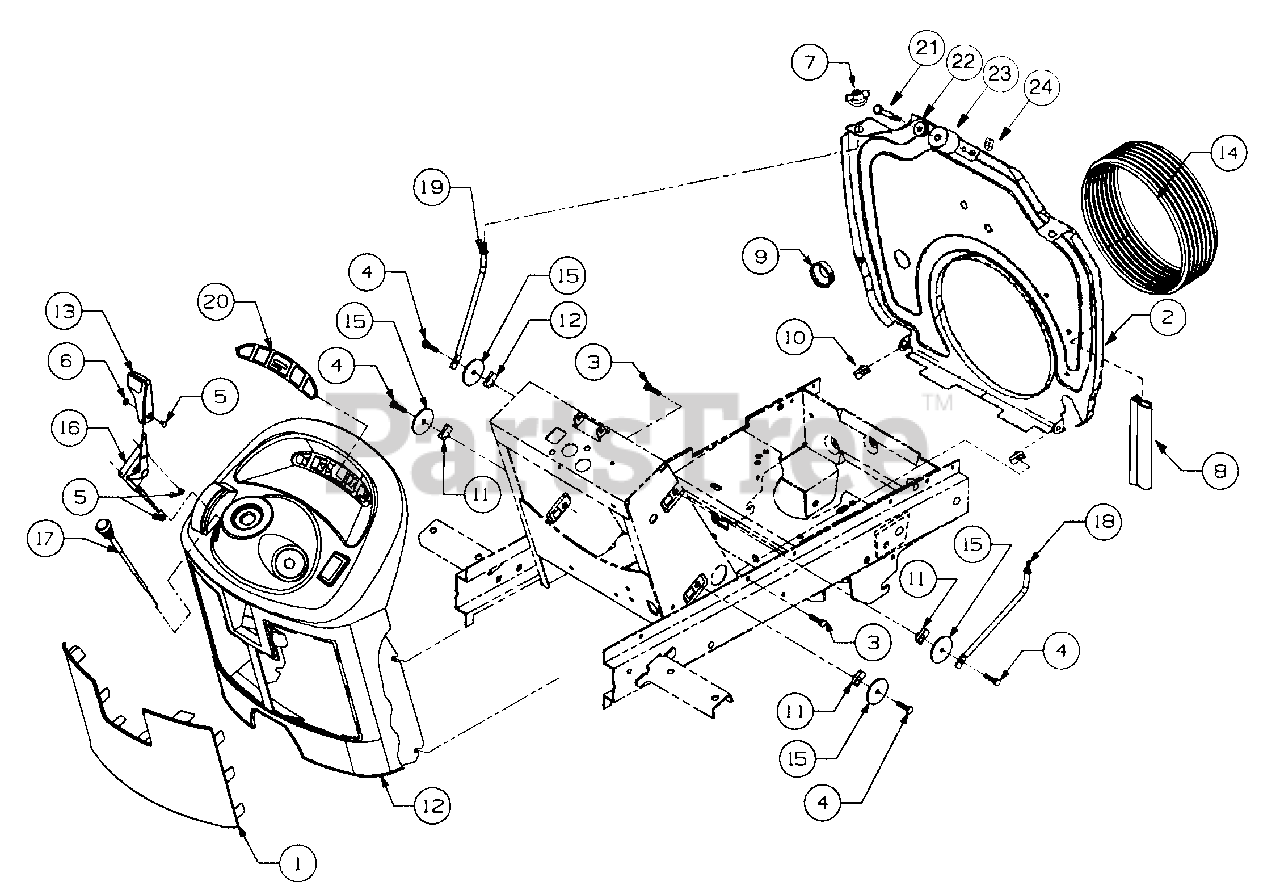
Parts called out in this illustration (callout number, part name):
2	Bulkhead, Lower
4	Screw, Hex Cap, 1/4-20 x 1.0
5	Screw, Cross Rec Truss Hd, #8-32 x.38
6	Nut, #8-32
7	Nut, Wing w/Bell Washer, 1/4-20
8	Seal, Push On Trim
9	Bushing, Snap, 7/8 ID
10	Nut, U-Type Speed, 1/4-20
11	Nut, U-Clip, 1/4-20
12	Panel Dash
13	Knob, Throttle
14	Boot, Intake
15	Washer, Flat, .285 x 1.75 x .10
16	Control, Throttle
17	Control, Choke
18	Rod, RH Mounting
19	Rod, LH Mounting
20	Label, Dash
21	Screw, Hex Cap,1/4-20 x 1.75 GR5
22	Washer, Flat, .283 x .75 x .030
23	Roller, Hood Latch
24	Nut, Hex Sems, 1/4-20
